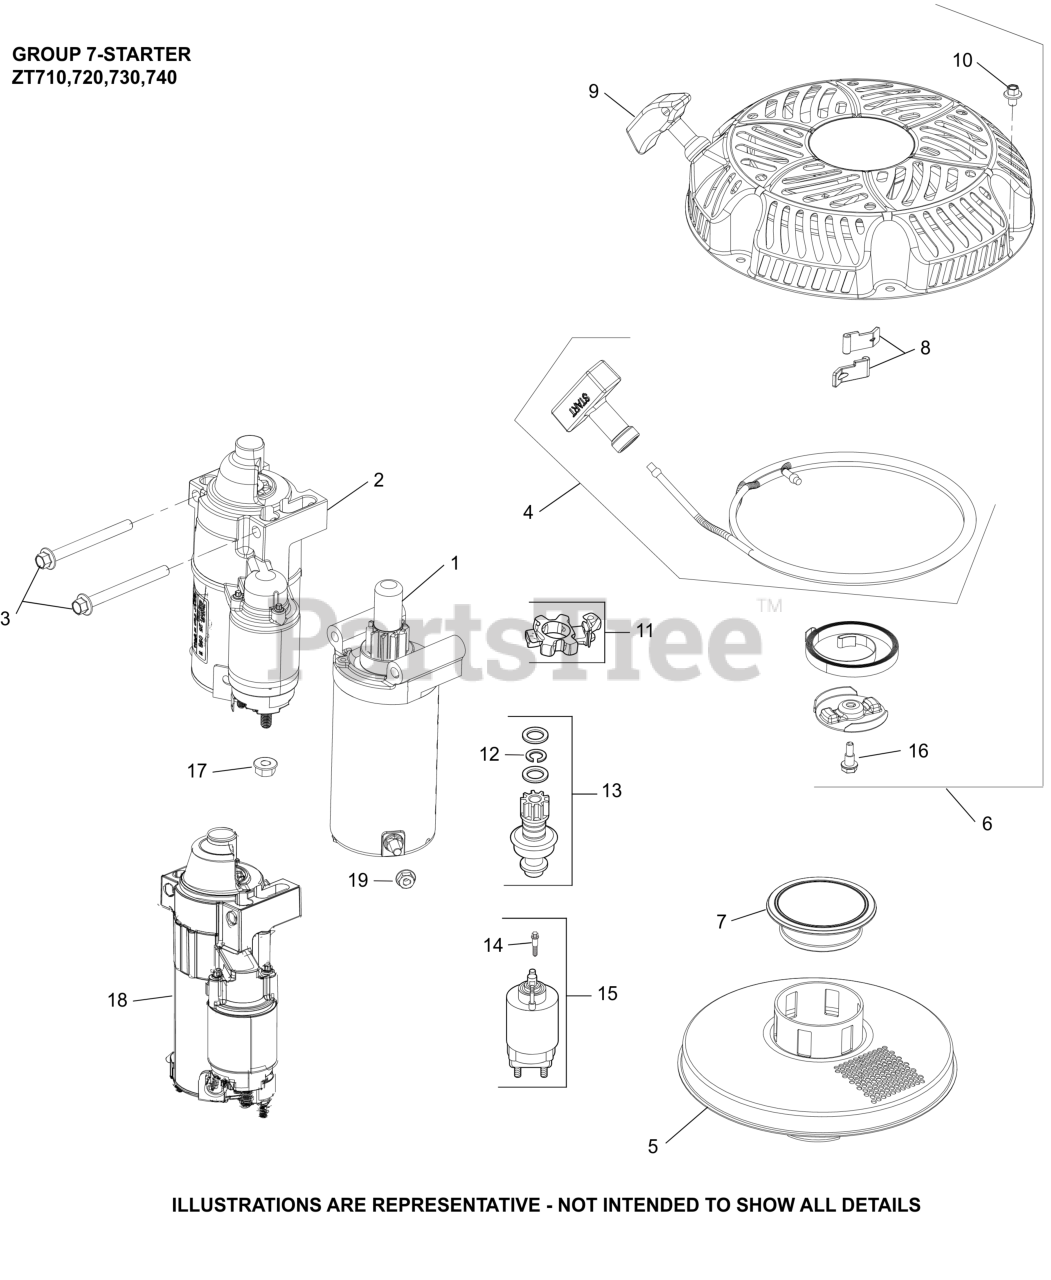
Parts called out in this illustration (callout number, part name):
2	STARTER, SOLENOID SHIFT
3	SCREW, FLG M8X1.25X80
17	NUT, FLG M8X1.25
